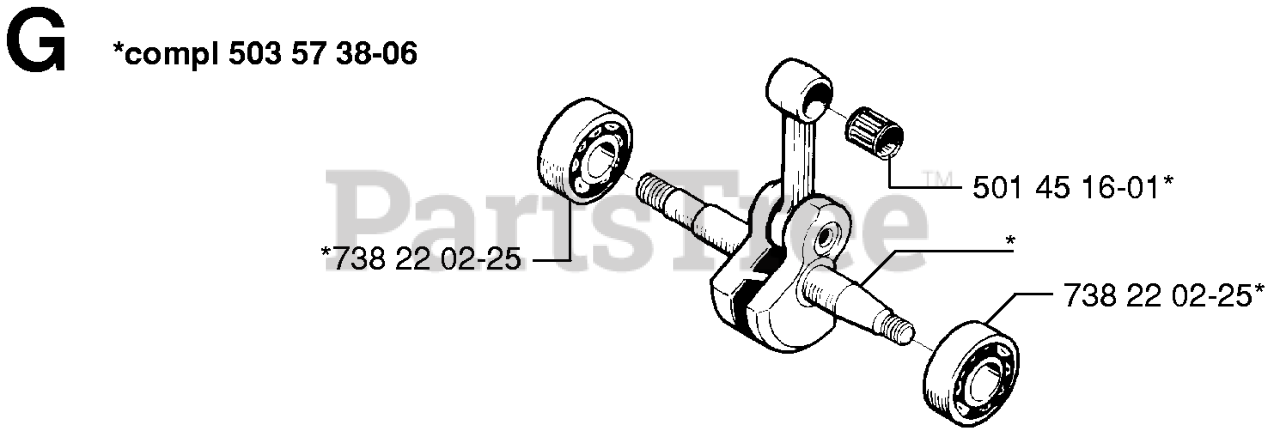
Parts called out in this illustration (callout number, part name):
74	Screws
75	Washers
267	Screws
332	Nuts
474	Generators
635	Spark Plugs
934	Screws
